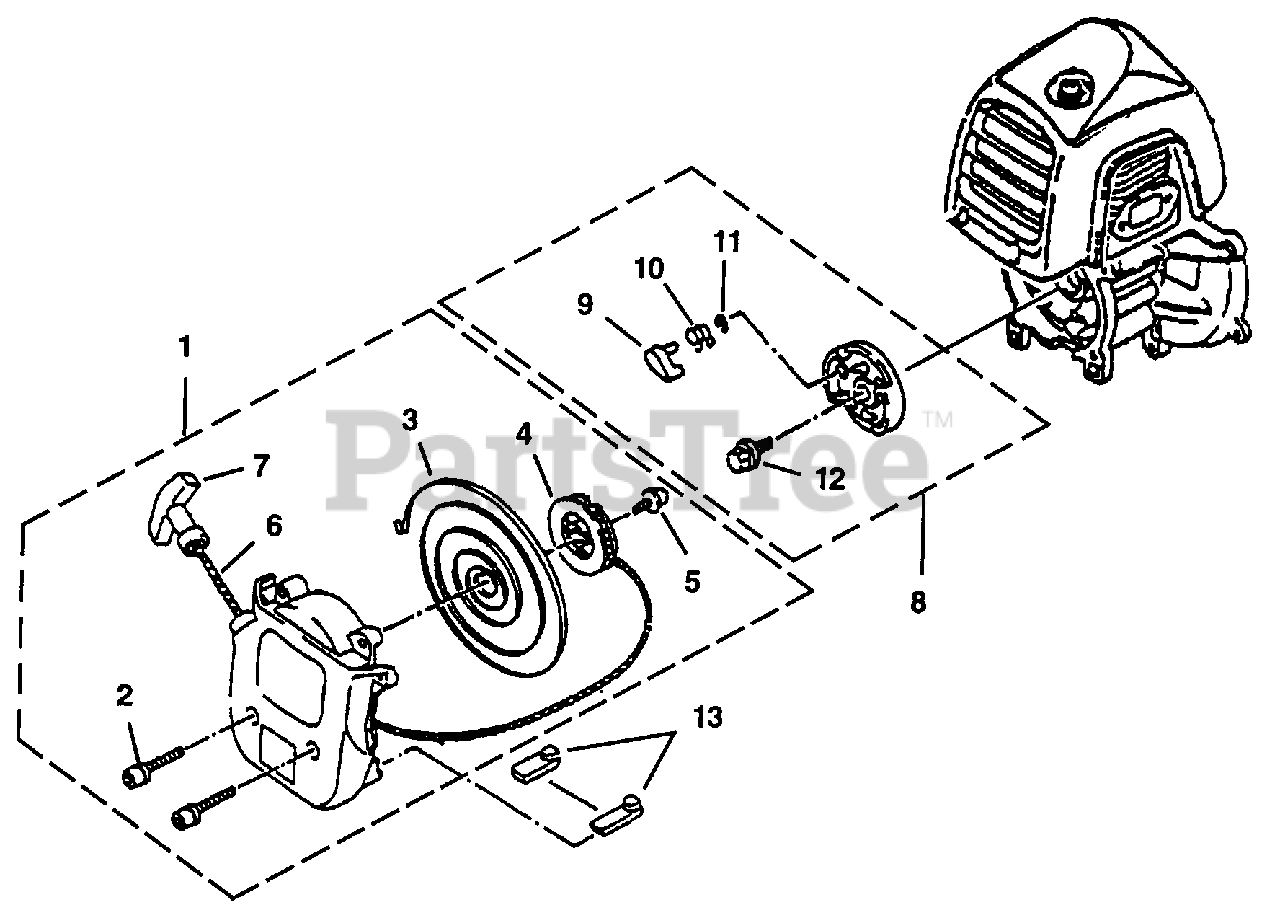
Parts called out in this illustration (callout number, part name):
1	STARTER COMPLETE
2	SCREW-Socket Hd (M5 x 30)
5	SCREW-Set
6	ROPE-Starter
8	STARTER CUP ASSEMBLY
10	SPRING-Return
12	BOLT ASSEMBLY
13	RUBBER BUMPER KIT
